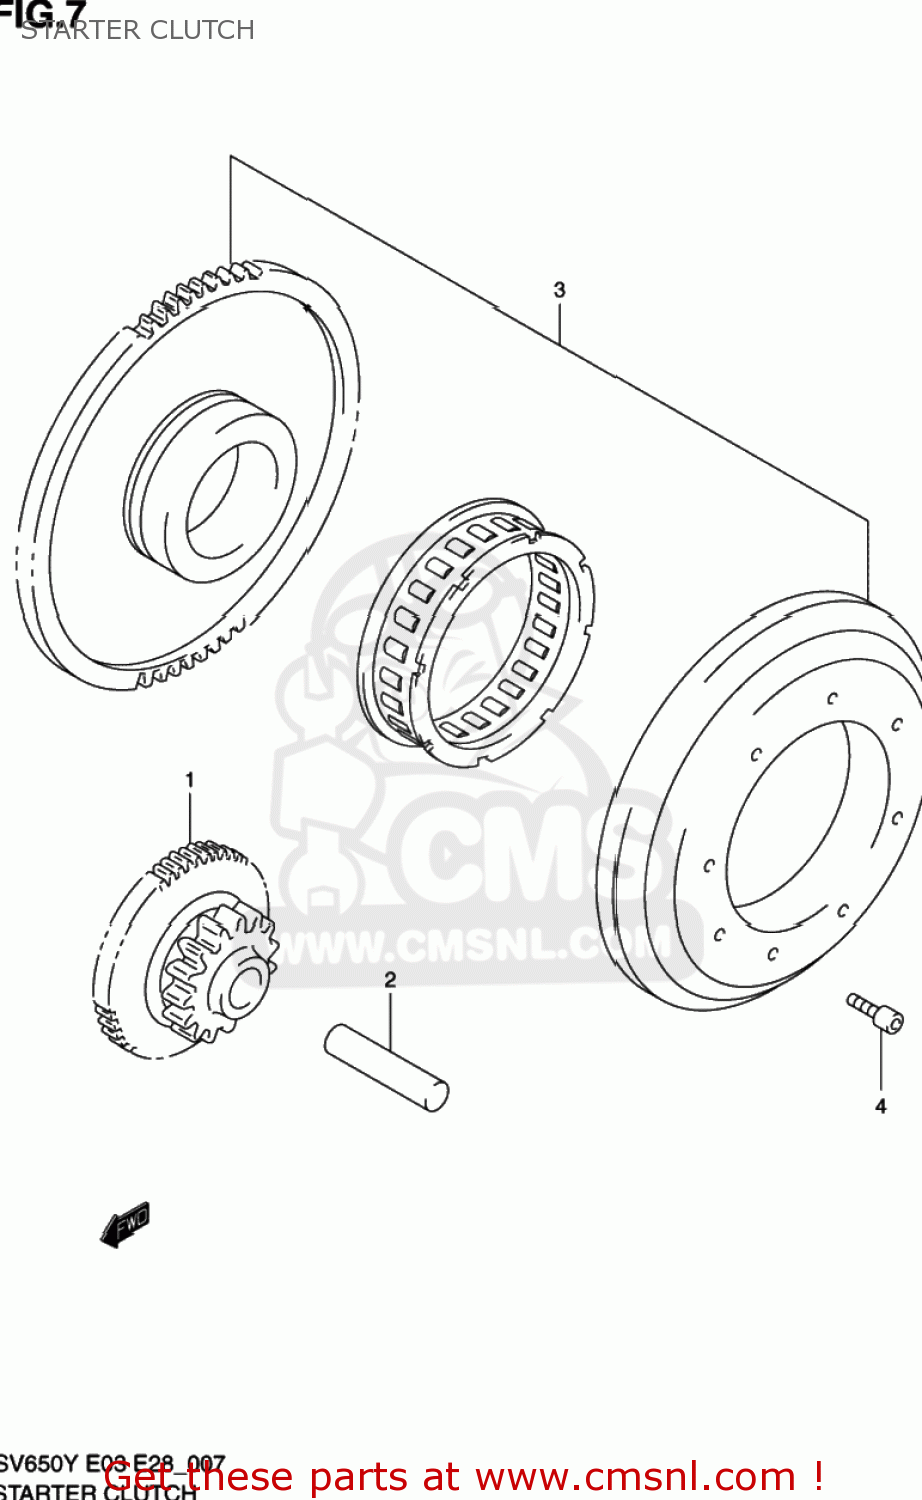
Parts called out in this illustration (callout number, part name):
1	GEAR,STARTER IDLE
2	PIN(12X46)
3	CLUTCH SET,STARTER
4	BOLT
